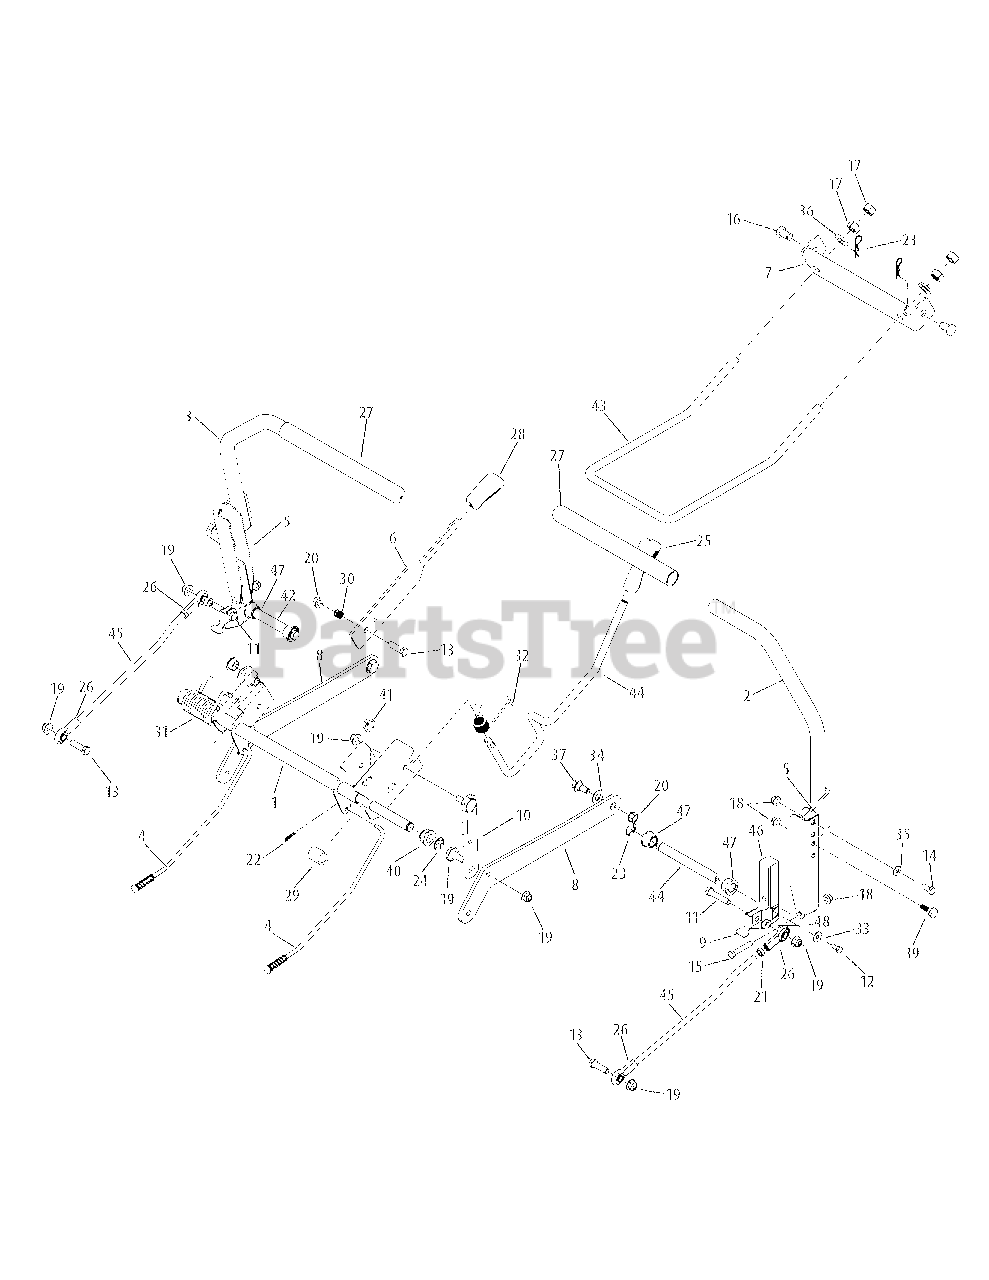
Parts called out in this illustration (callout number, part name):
1	Deck Lift Shift Assembly
2	RH Lapbar Lever Assembly
3	LH Lapbar Lever Assembly
4	Brake Rod Assembly
5	Lapbar Pivot Bracket
6	Brake/Shabs Handle
7	Front Deck Hanger Bracket
8	Deck Lift Arm Plate
9	Switch Actuator Bracket
10	Lift Link Plate
11	Hex Screw, 3/8-16 x 1.75
12	Hex Screw, 1/4-20 x .625
13	Hex Screw, 3/8-16 x 1.25
14	Hex Screw, 5/16-18 x .75
15	Hex Screw, 5/16-18 x 1.75
16	Clevis Pin, .50 x .78
17	Hex Nut, 1/2-13
18	Flange Lock Nut, 5/16-18
19	Flange Lock Nut, 3/8-16
20	Flange Lock Nut, 3/8-16
21	Jam Nut, 3/8-24
22	Cotter Pin, .072 x 1.13
23	Cotter Pin, .080 x 1.5625
25	Handle Grip
27	Lapbar Grip
28	Selector Handle
29	Spacer, .621 x 1.00
30	Compression Spring, .50 x .50
31	Torsion Spring, 1.19 x 2.78
32	Spring, Torsion RZT
33	Bell Washer, .265 x .75 x .062
34	Flat Washer, .510 x 1.00 x .060
35	Flat Washer, .344 x .688 x .065
36	Flat Washer, .531 x 1.062 x .134
37	Shoulder Bolt, 3/8-16 x .496 x .336
39	Shoulder Screw, .500 x .434
40	Hex Flange Bearing
41	Flange Bearing, .626 x .938 x .344
42	Shift Control
43	Front Hanger Deck Lift Rod
44	Deck Lift Handle Rod
45	Lapbar Rod Control
46	Control Hub
47	Hex Flange Bearing
48	Spacer, .380 x .625 x .265
